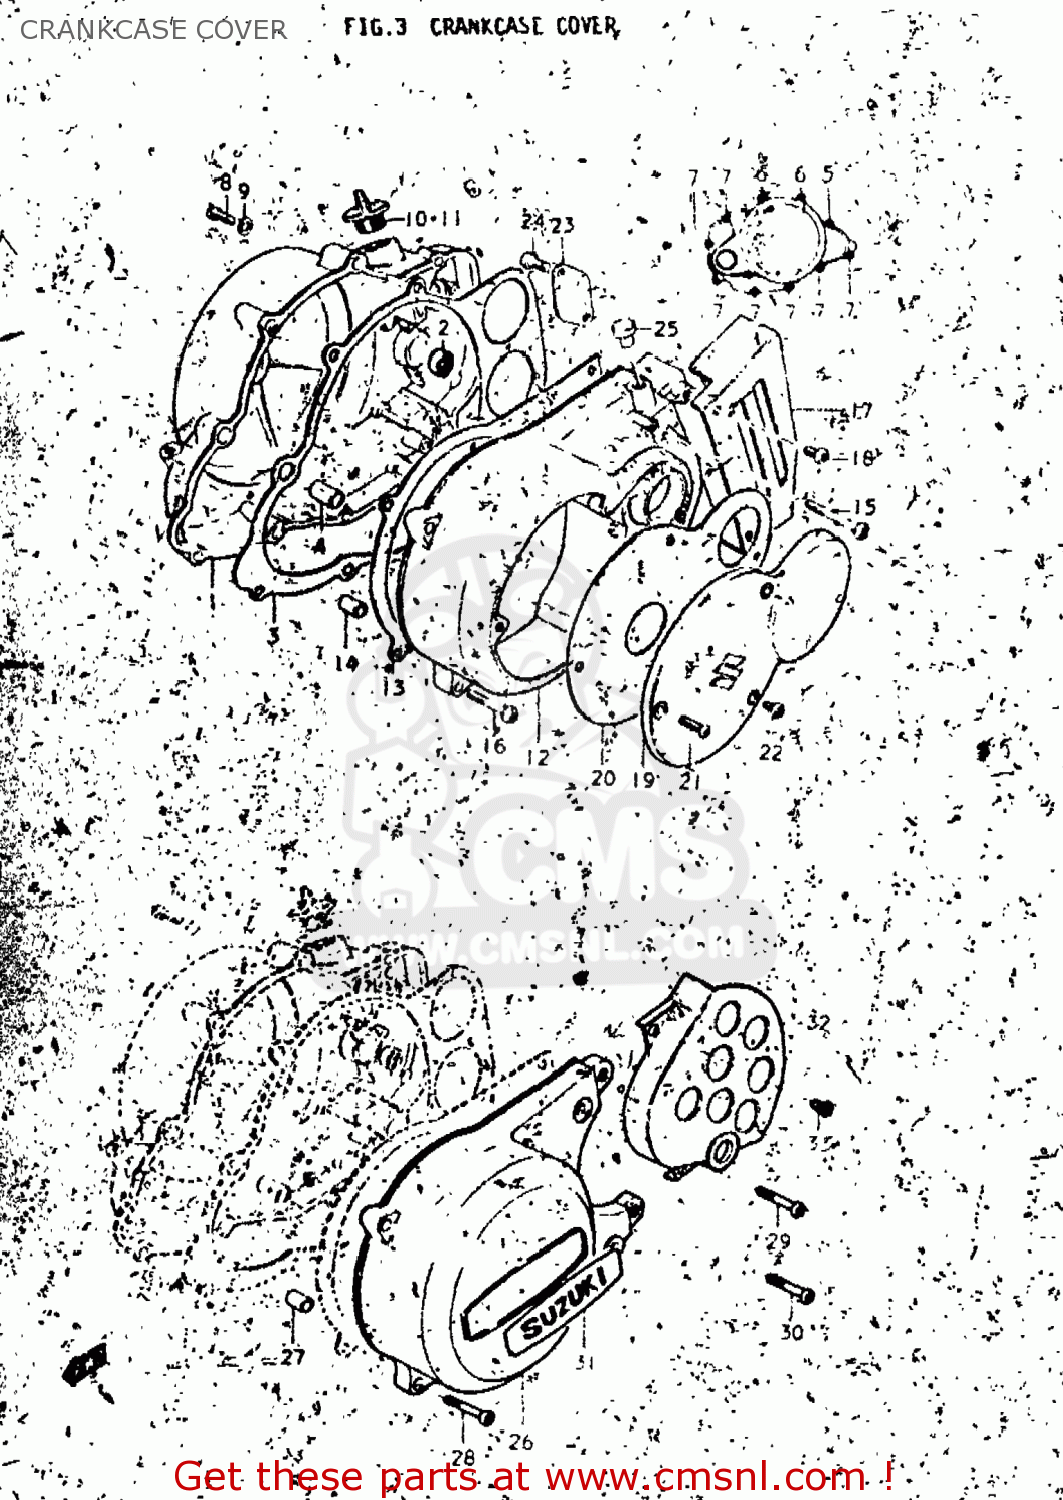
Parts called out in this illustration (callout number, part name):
1	COVER,CLUTCH
2	BEARING
3	GASKET,CLUTCH COVER (MCA)
4	PIN
5	SCREW (6X45)
6	SCREW (6X35)
7	SCREW
8	SCREW(6X10)
9	GASKET(6.2X11X1) (NAS)
10	PLUG,OIL FILTER
11	PLUG
12	COVER
13	GASKET,MAGNETO COVER (NAS)
14	PIN
15	SCREW
16	SCREW
17	COVER,SPROCKET
18	SCREW
19	CAP,MAGNETO INSPECTION
20	GASKET,MAGNETO INSPECTION (NAS)
21	SCREW
22	SCREW
23	CAP,CLUTCH RELEASE ADJUST
24	SCREW 6X12
25	CAP
26	COVER,MAGNETO
27	PIN
28	SCREW
29	SCREW
30	SCREW
31	EMBLEM
32	COVER,SPROCKET
33	SCREW
